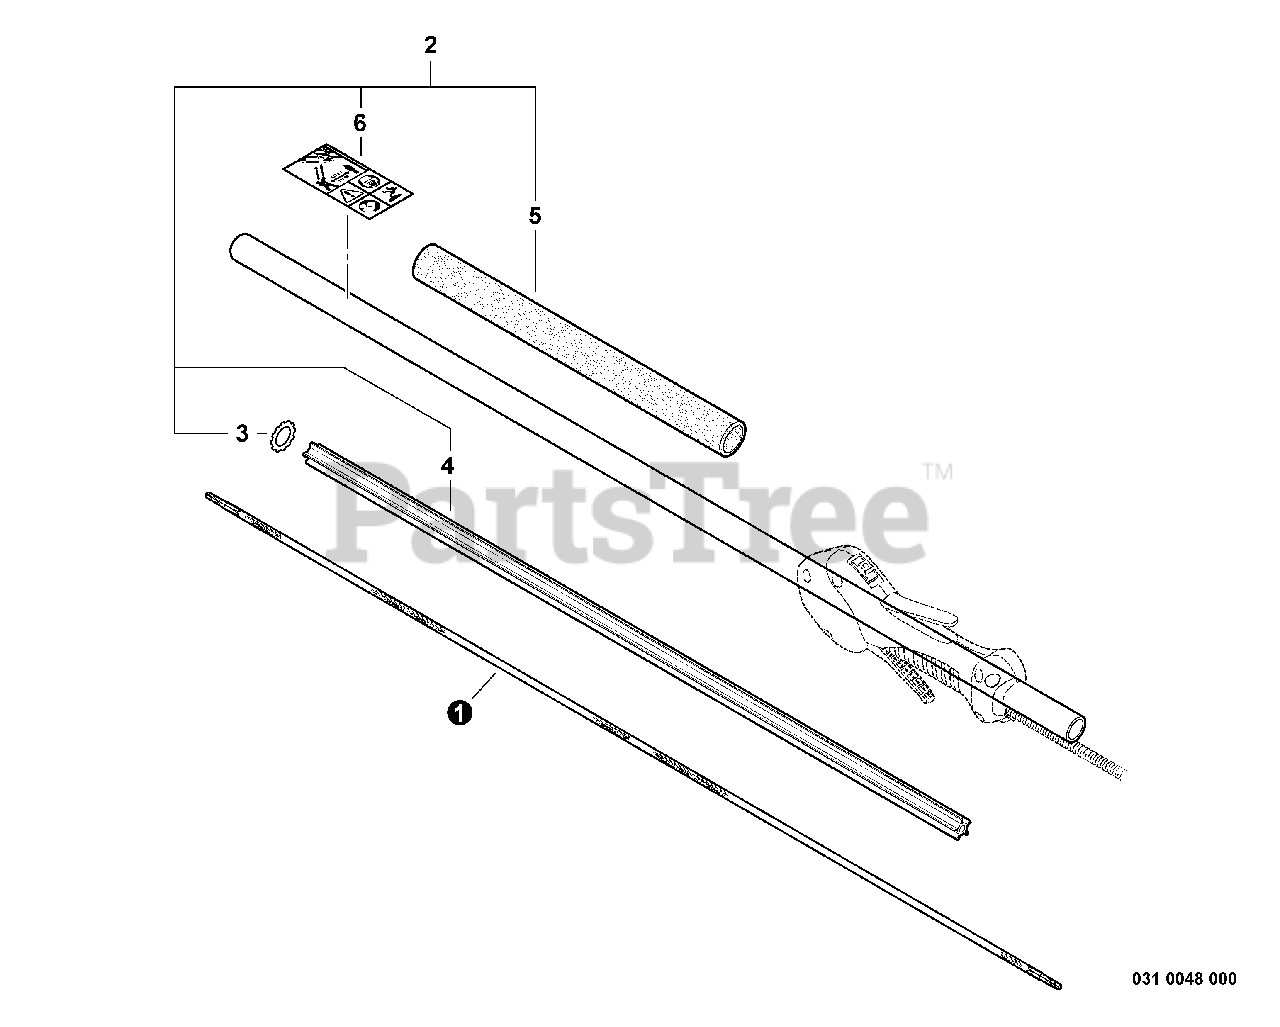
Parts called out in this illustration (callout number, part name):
1	DRIVESHAFT - FLEXIBLE
2	MAIN PIPE ASSY
4	LINER - FLEXIBLE
5	GRIP, FRONT
6	LABEL, CAUTION
